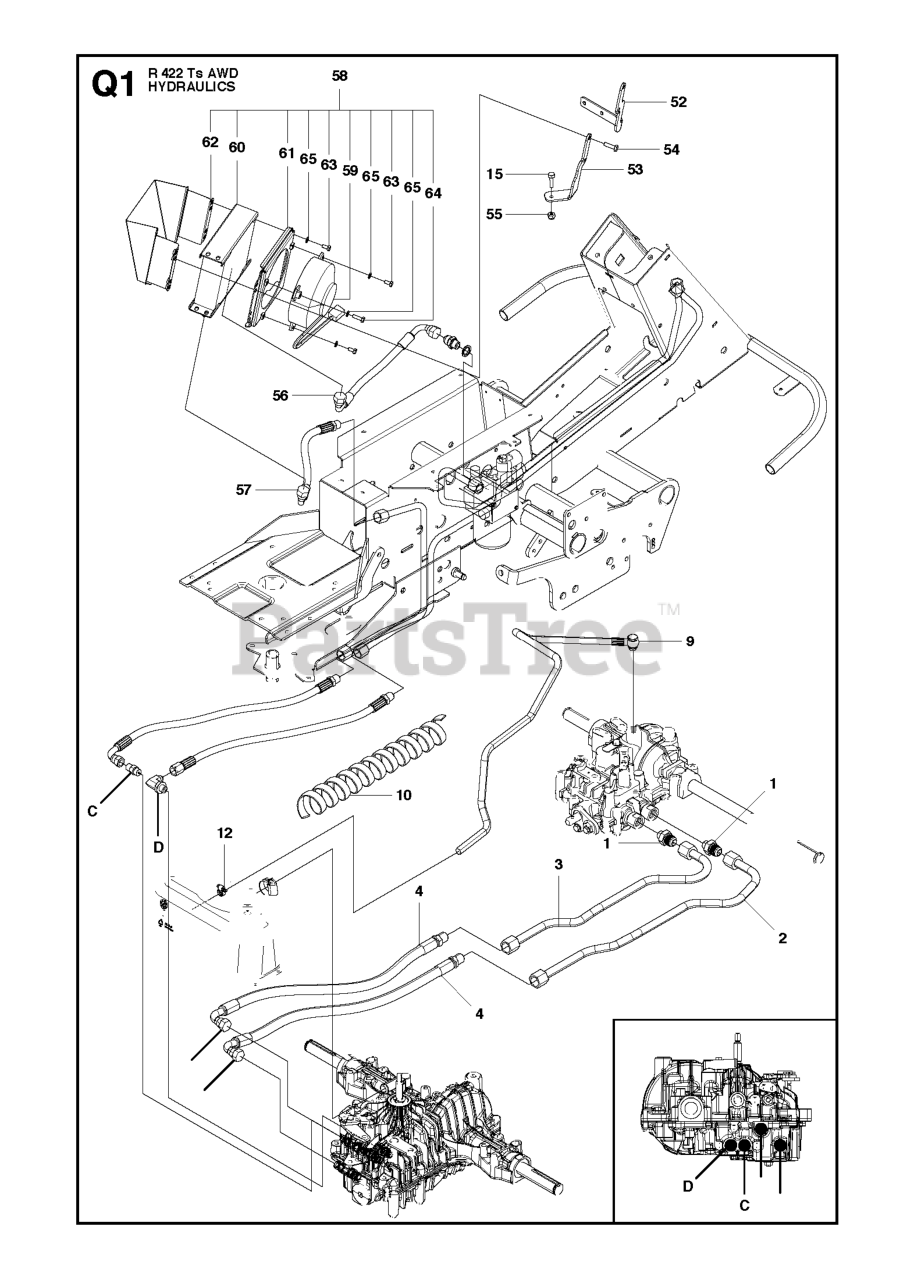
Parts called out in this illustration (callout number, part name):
1	PIPE FITTING
10	HOSE GUARD
15	BOLT FLANGE - M6X20
54	SCREW EHHFM
55	LOCKNUT M6
65	WASHER - M6
